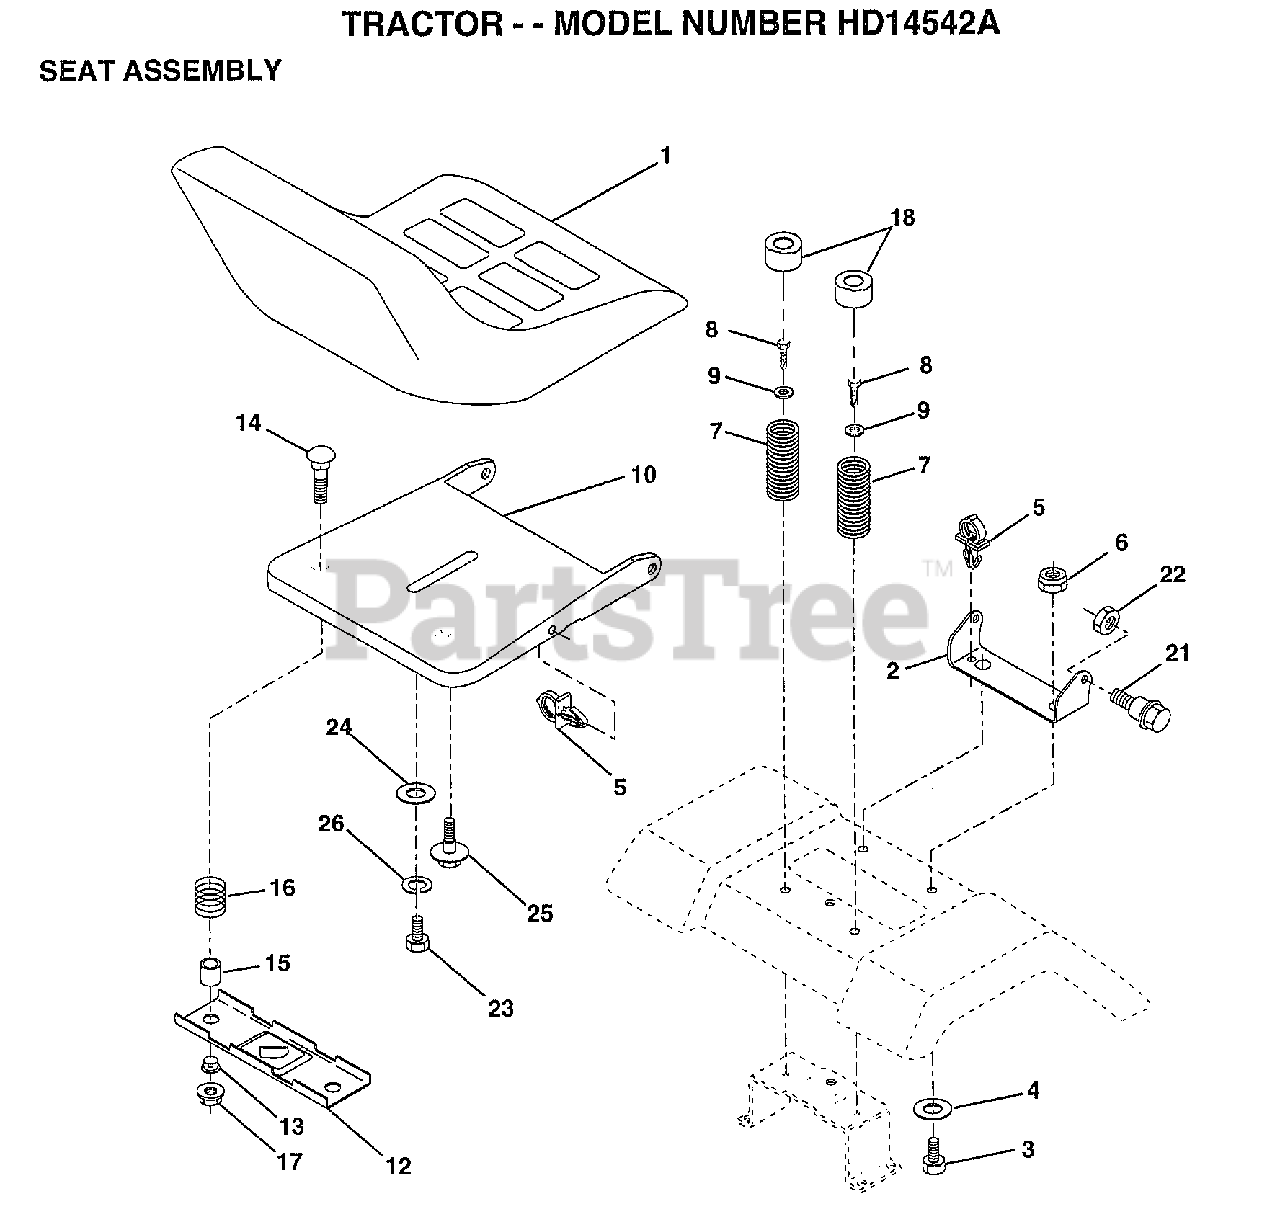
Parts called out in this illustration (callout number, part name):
1	SEAT
2	BRACKET PVT SEAT
3	BOLT
4	WASHER PM
5	CLIP.PUSH-IN.HING
6	NUT
7	SPRING COMPRESSIO
8	SCREW GTV
9	WASHER
10	PAN-SEAT
12	BRKT SWITCH
13	BUSHING
14	BOLT-RD HD SQ NK
15	SPLIT SPACER
16	SPRING
18	CAP SPRING
21	"BOLT,SHOULDER"
22	NUT
23	BOLT
24	WASHER
25	"BOLT,SHOULDER"
26	LOCKWASHER
